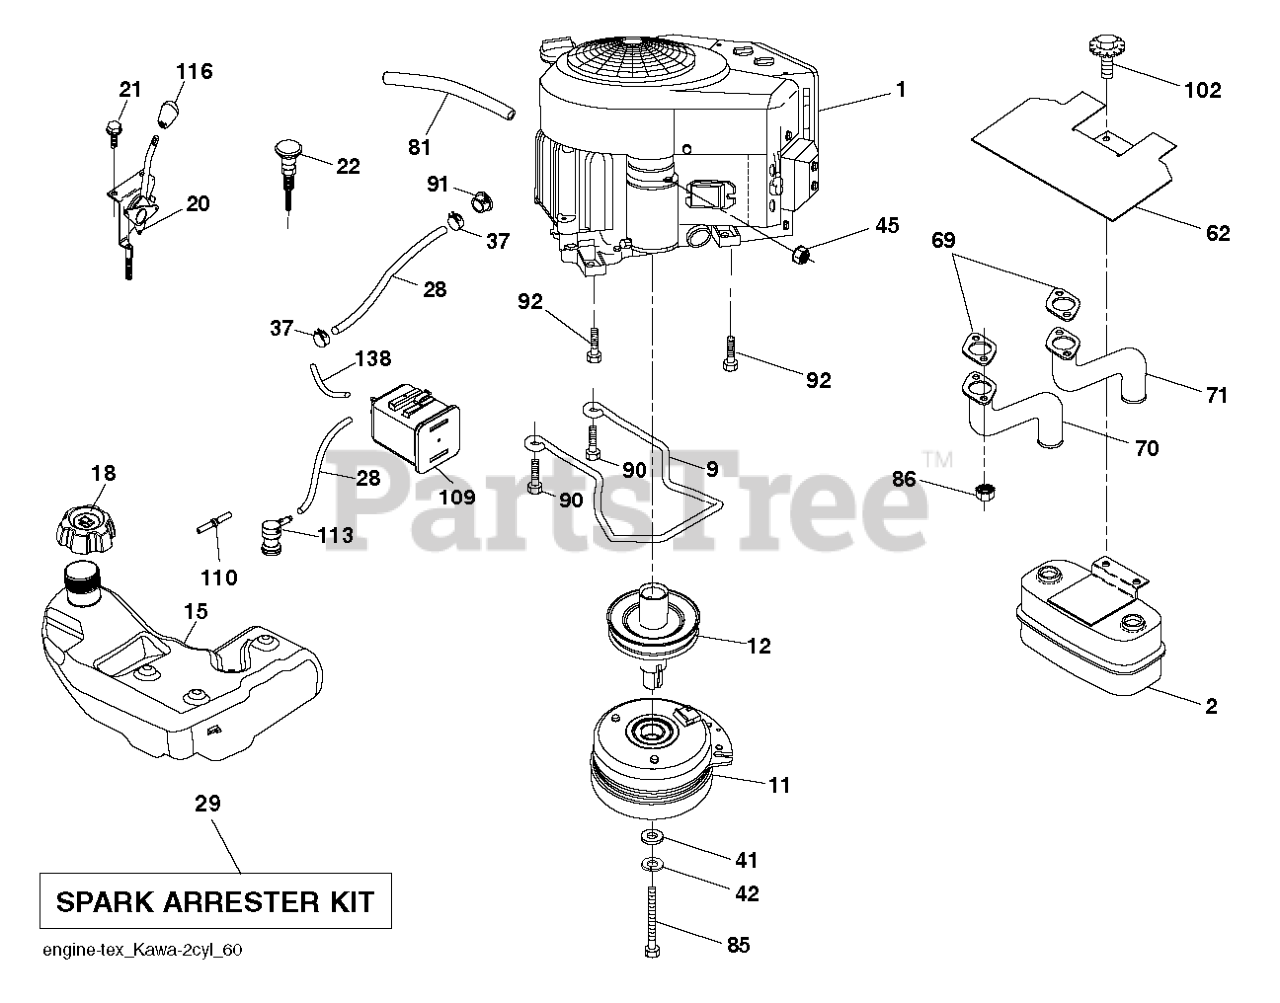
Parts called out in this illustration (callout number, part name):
2	MUFFLER.ASM.TWIN.MNTG.BRACKET
9	KEEPER.BELT.ENG.4.25"2.BLT.431
11	CLUTCH. 5.0 PD. 2.5 OFFSET
12	PULLEY.EXTENDED.SHAFT.GROUND
15	FUEL TANKS
18	FUEL CAP
18	CAP ASSY FUEL 3" GRAY
20	CONTROL.THROTTLE.PRO.
21	SCREW.#10X.750
22	CONTROL, CHOKE
28	LINE.FUEL.64"REAR.EMIS
29	KIT.SPARK ARRESTOR 794945 B&S
37	HOSE CLAMP
62	SHIELD.HEAT.MUFFLER
70	TUBE.EXHAUST.LH.FR961/FR730
71	TUBE.EXHAUST.RH.FR961/FR730
81	TUBE, DRAIN OIL ASM.
85	BOLT.HEX.7/16-20X5.GR5.GREEN
86	NUT.HEX.FLANGE.TOPLOCK
90	SCREW 3/8-16X1
91	BUSHING.1.375OD
92	SCREW 3/8-16X1
102	SCREW
109	CANNISTER, CARBON
110	VALVE.ASM.ANTI-SLOSH
113	VALVE.SLANT.CARTRDG.90 DEG.TEX
116	KNOB - SHIFT
138	PURGE.LINE.36"REAR.CALIFORNIA
